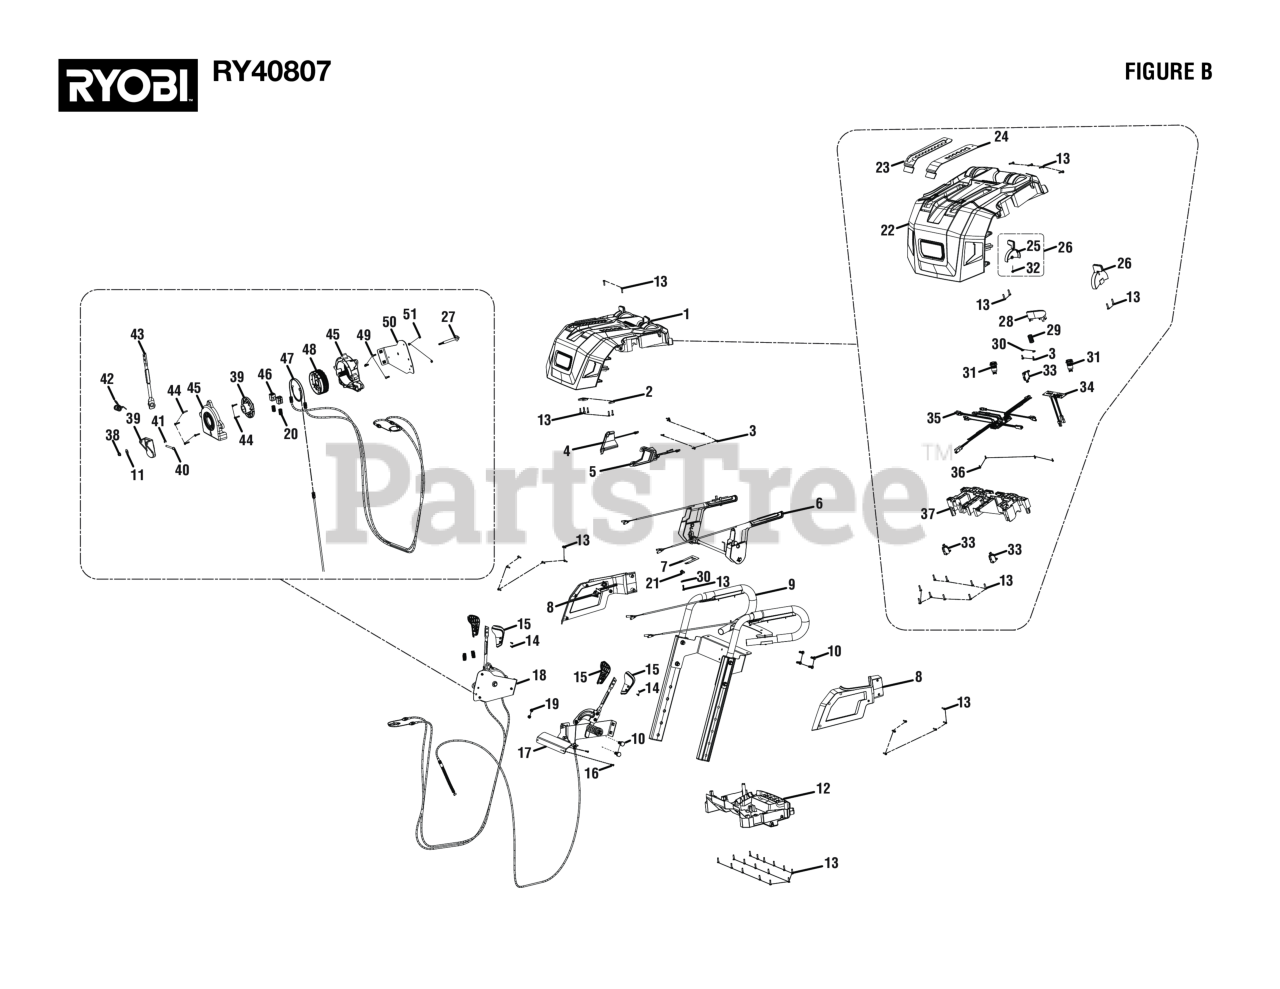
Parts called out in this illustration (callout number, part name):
1	Upper Handle Control Plate Assembly
2	Wire Press Plate
3	Screw (M4.2 x 12 mm, T20 Torx Pan Hd.)
4	Light Bar Assembly (Right)
5	Light Bar Assembly (Left)
6	Paddle Interlock Master Assembly
7	Interlock Spring
8	Control Panel Side Cover
9	Handle Bracket Assembly
10	Screw (M6 x 14 mm)
11	Washer (ID8.4 x OD18 x 1t)
12	Control Panel Base
13	Screw (M4 x 18 mm, T20 Torx Pan Hd. S.T.)
14	Screw (M3 x 12 mm, Pan Hd.)
15	Height Adjustment Assembly
16	Screw, T20, M4-18X12, Low Carbon Steel,
17	Upper Deflector Adjust Assembly
18	Upper Chute Control Assembly
19	Lock Nut (M6 x 6 mm)
20	Cable Drum Spring
21	Spring Clamp
22	Control Panel Cover with Labels
23	Chute Ratation Lock Plate
24	Deflector Height Adjust Lock Plate
25	Speed Control Paddle Bottom Assembly
26	Speed Control Paddle Bottom Assembly
27	Bolt (M5)
28	Safety Button
29	Safety Button Spring
30	Flat Washer (OD10 x ID42 x 1t)
31	Control Panel Switch with Labels
32	Screw (M3 x 8 mm, Pan Hd., Pan Hd)
33	Micro Switch
34	Control Board, Battery And Display Assembly
35	Control Board Assembly
36	Screw (M3 x 8 mm, Pan Hd., Pan Hd)
37	Upper Handle Mounting Bracket
38	Flange Lock Nut (M5 x 0.8 in.)
39	Drum Assembly
40	Hinge Shaft
41	Retaining Ring (4 mm)
42	Chute Rotation Lever Torsion Spring
43	Bar Adjust
44	Screw (M4 x 18 mm, T20 Torx Pan Hd. S.T.)
45	Upper Chute Rotation Assembly
46	Cable Tension Sleeve
47	Control Cable
48	Upper Cable Drum
49	Bolt (M4 x 12 mm, Pan Hd.)
50	Chute Adjust Support Bracket
51	Lock Nut (M4)
